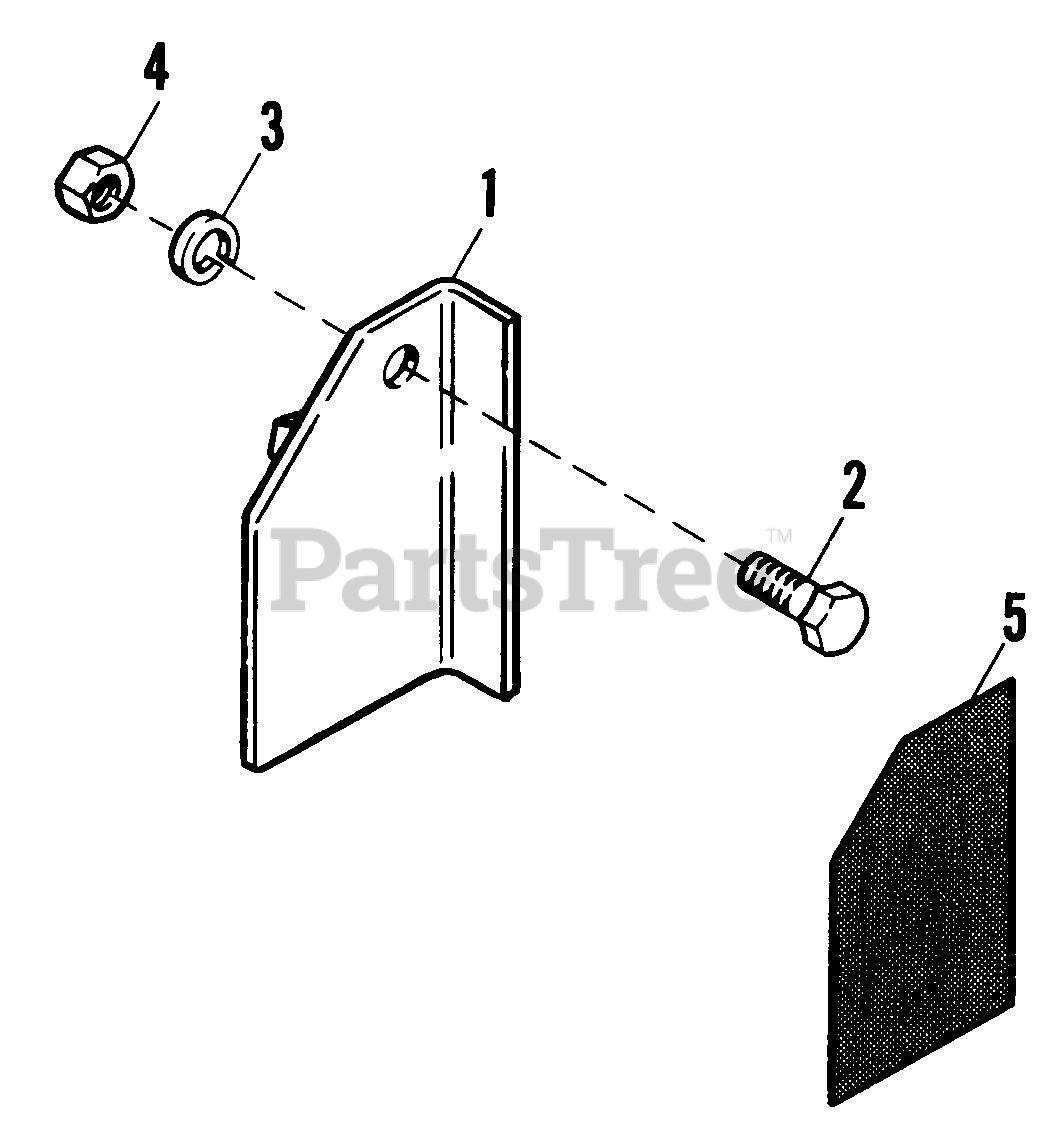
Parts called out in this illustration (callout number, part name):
1	STOP ASSY., (Six-Speed) STOP ASSY., (Hydro)
2	CAPSCREW, Hex, 5/16-18 x 3/4
3	LOCKWASHER, 5/16
4	NUT, Hex, Full, 5/16-18
5	DECAL, Adjustment
